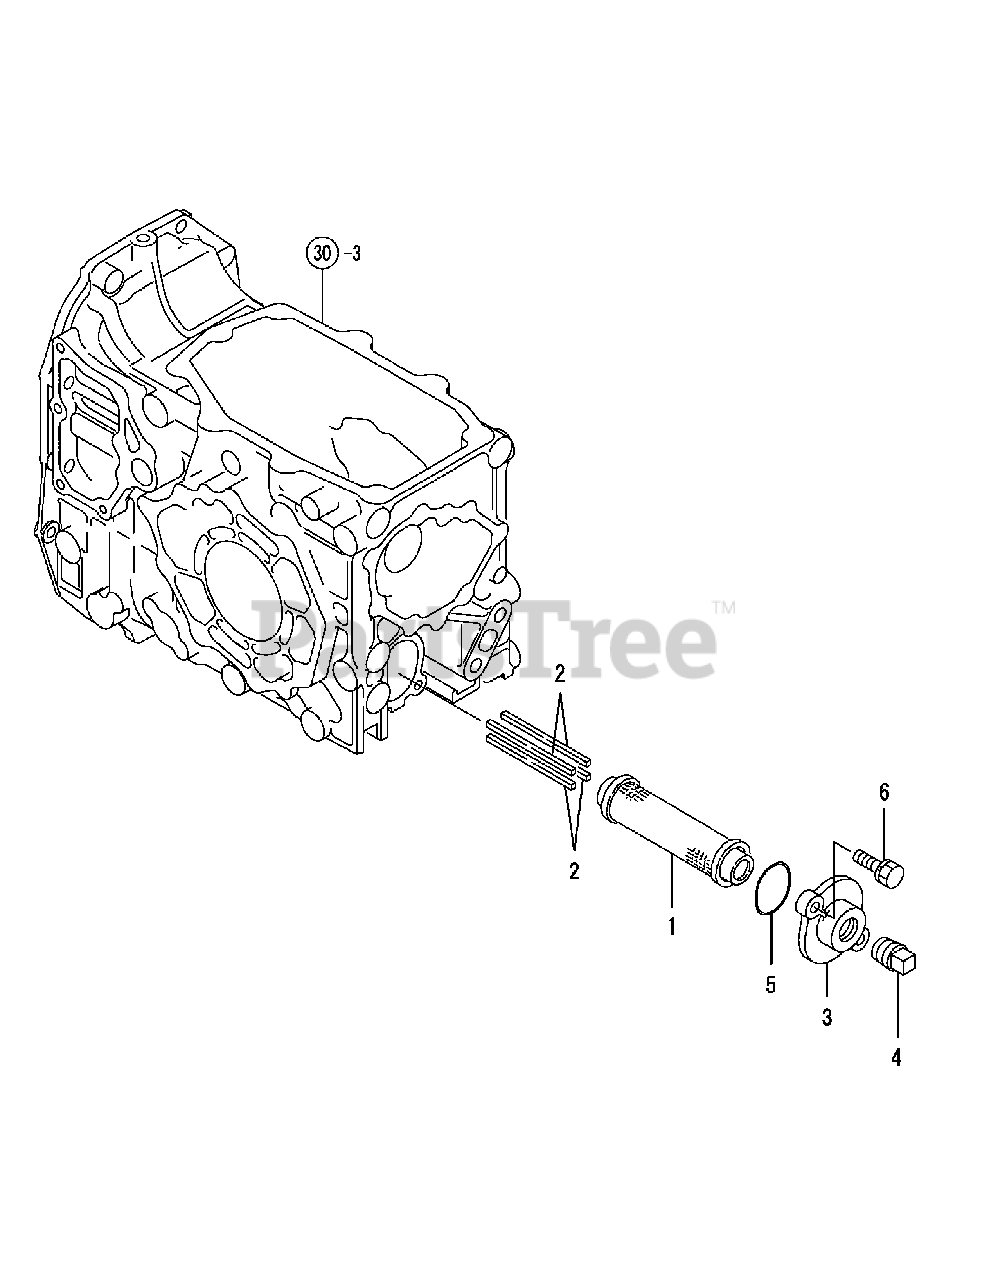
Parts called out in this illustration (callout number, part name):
1	Strainer,Oil Hydraulic
2	Magnet, Filter Hydraulic
3	Cover, Oil Strainer
5	Packing,Suction
